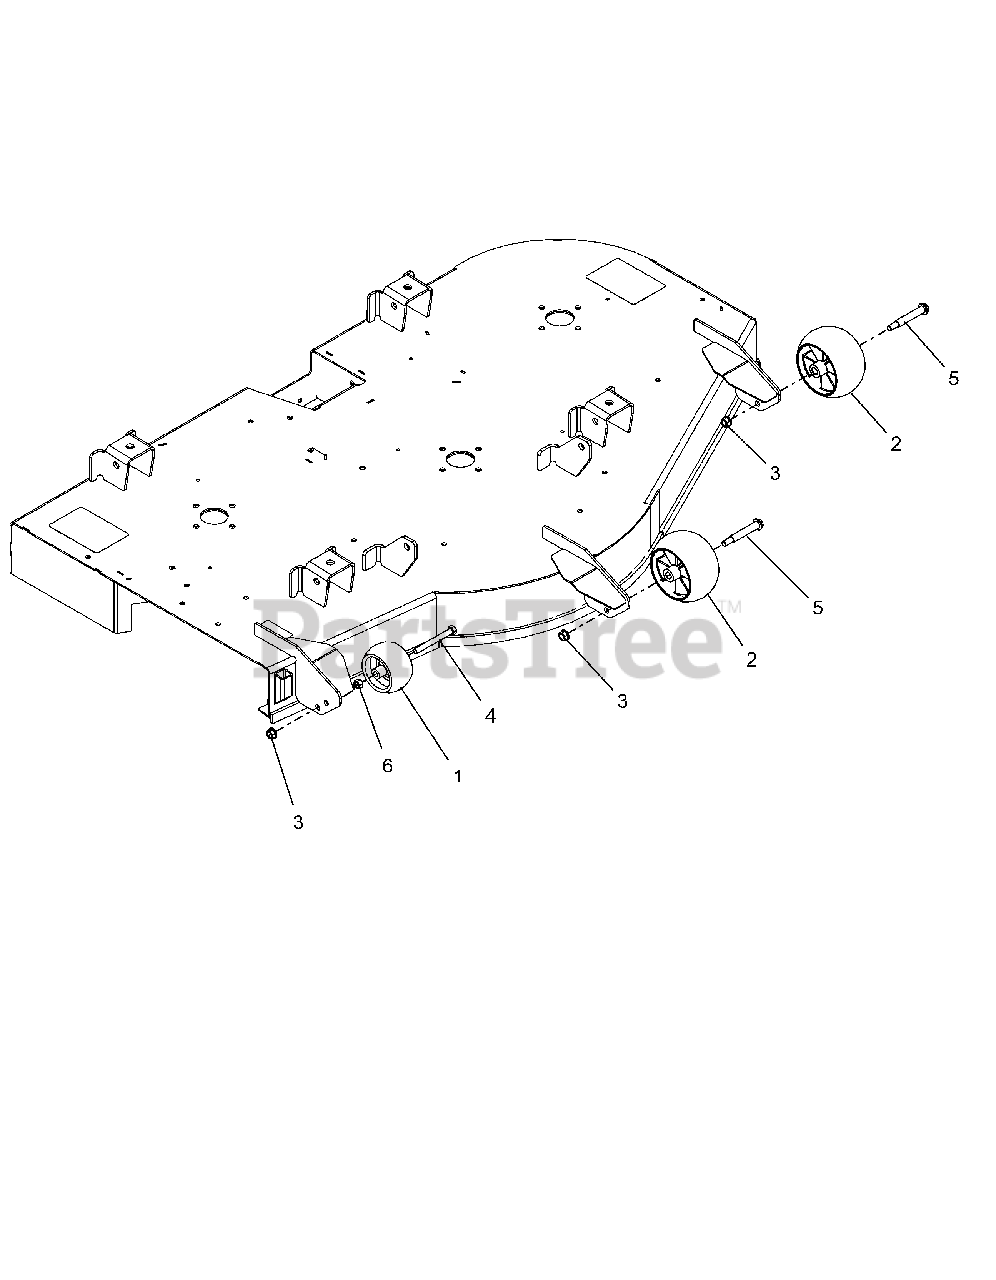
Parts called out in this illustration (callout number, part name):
2	ANTI-SCALP WHEEL - 5X OS
3	NUT-LK-TOP-FLG .38-16 ZC120
4	BLT, HEX .38-16X3.50 G5 ZCC
5	BLT-SHLDR .38-16X2.50 HWH G5
6	@NUT-HEX .38-16 YWZC
